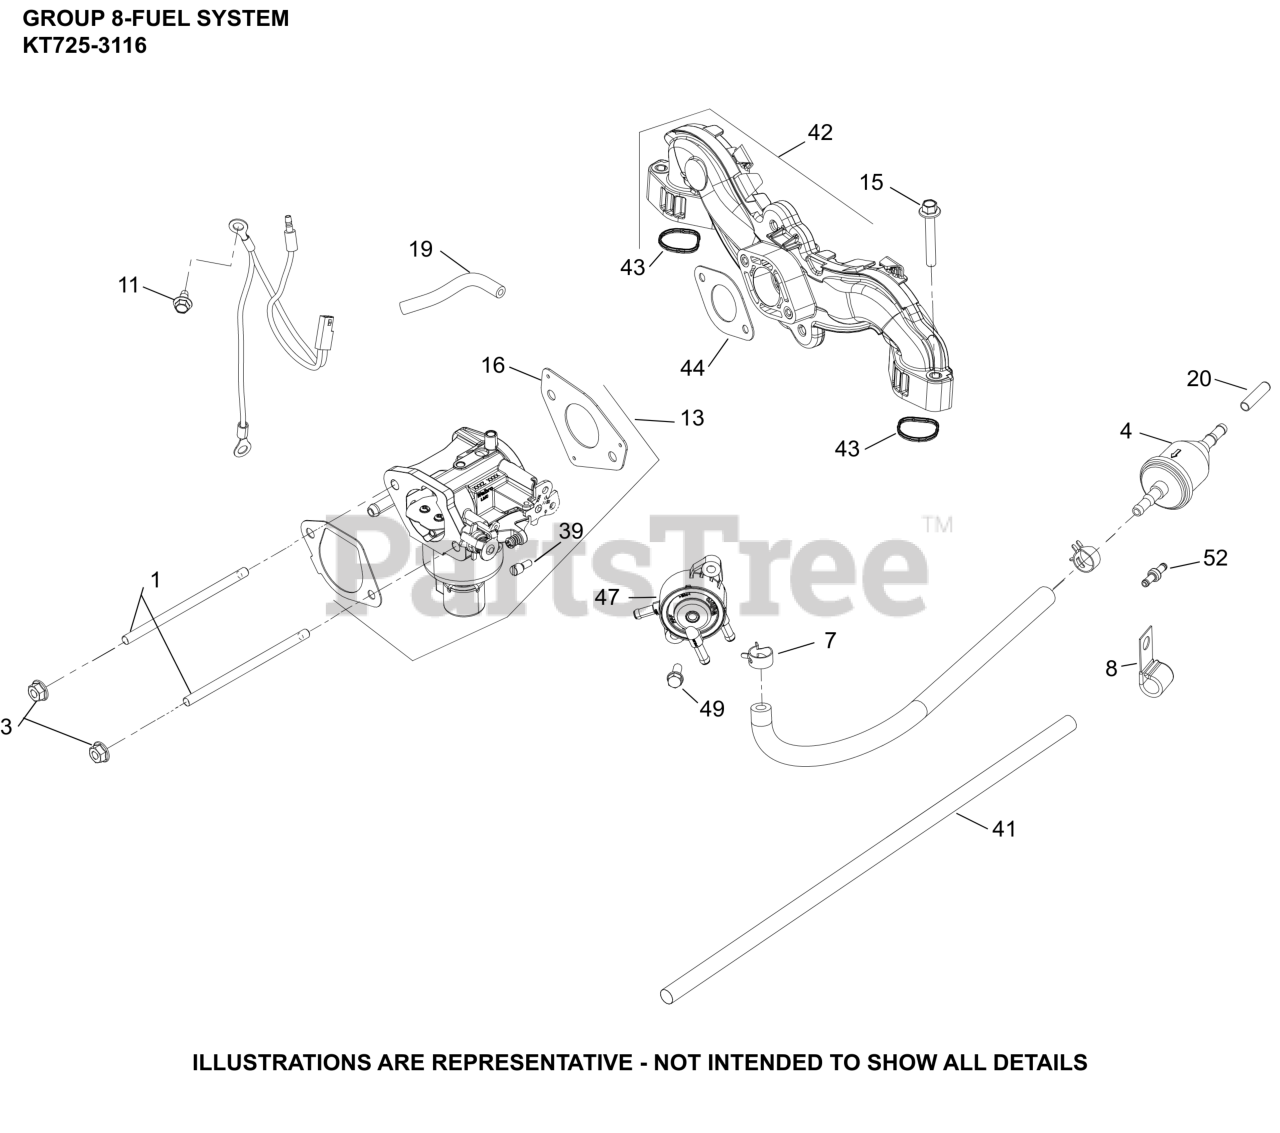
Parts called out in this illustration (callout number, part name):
3	NUT, FLG M6X1.0
4	FILTER,FUEL 51 MICRON (FUEL PUMP)
7	SPRING CLAMP, HOSE
8	CLIP, CABLE (KM)
11	SCREW, THREAD FORMING
13	KIT,CARB(WALBRO)
15	SCREW, FLG M6X1.0X40
16	GASKET, CARBURETOR-(#2404191S)
19	HOSE, EVAPORATIVE 20"- (#24326143S)
20	CAP, MASKING
39	SCREW, THROTTLE STOP
41	SLEEVE, ANTI-ABRASION
42	INTAKE MANIFOLD W/GASKETS
43	O-RING, INTAKE PORT
44	GASKET, CARBURETOR (PIM, CV)
47	PUMP, FUEL (PULSE)
49	SCREW, HEX HEAD
52	FITTING, FUEL SYSTEM
NI	KIT,REPAIR OVERHAUL(WALBRO)
NI	KIT,BOWL O-RING(WALBRO)
NI	KIT, HIGH ALT (4000-8000 FT)(WALBRO)
NI	KIT,SOLENOID REPAIR(WALBRO)
NI	KIT,REPAIR FLOAT(WALBRO)
